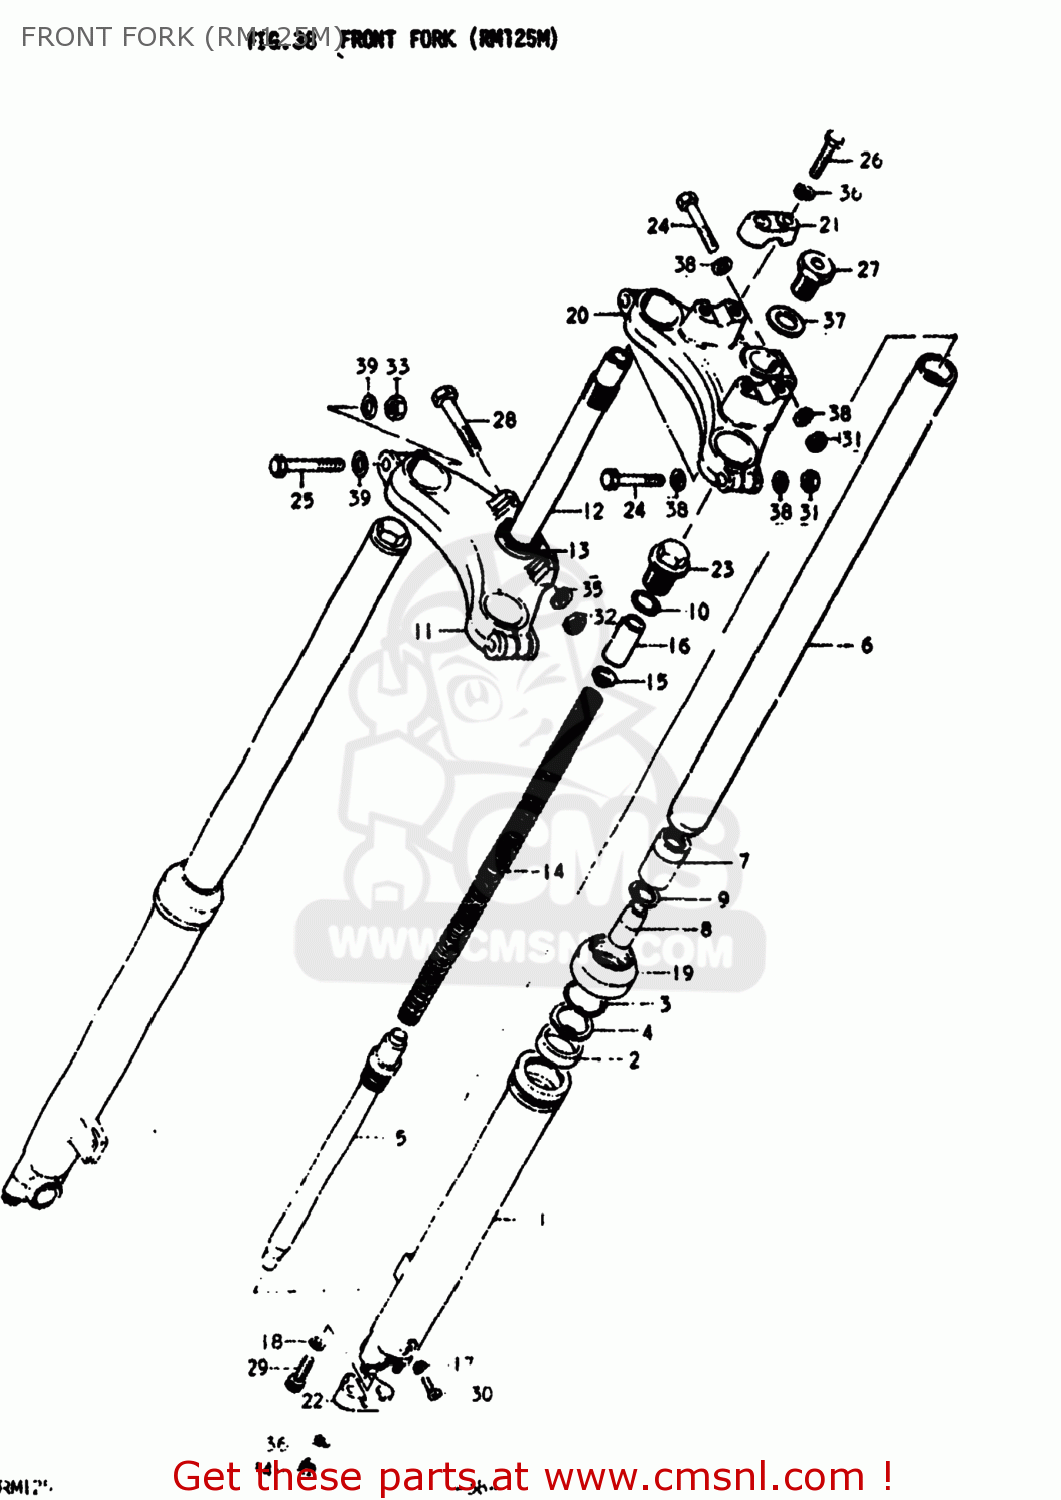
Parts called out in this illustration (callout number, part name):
1	TUBE,OUTER,LEFT
2	SEAL,OIL
3	CIRCLIP,FORK OIL SEAL
4	RING,FORK BACK UP
5	CYLINDER,FRONT FORK
6	TUBE,FORK,INNER
7	PISTON,FORK INNER TUBE
8	PIECE,OIL LOCK
9	RING
10	O RING
11	STEM,STEERING
12	STEM,STEERING
13	RACE,STEERING OUTER LWR
14	SPRING
15	GUIDE,FRONT FORK SPRING C
16	SPACER,SPRING
17	GASKET,DRAIN,PLUG (NAS)
18	GASKET (NAS)
19	SEAL,DUST
20	HEAD,STEERING STEM
21	HOLDER,HANDLEBAR
22	HOLDER,AXLE
23	BOLT,FORK
24	Bolt 8X50
25	BOLT
26	Bolt
27	CAP
28	BOLT
29	BOLT,FORK CYLINDER(10X25)
30	SCREW
31	NUT
32	NUT
33	NUT
34	NUT (8MM)
35	LOCK WASHER
36	LOCK WASHER
37	WASHER,STEM HEAD
38	WASHER
39	WASHER
